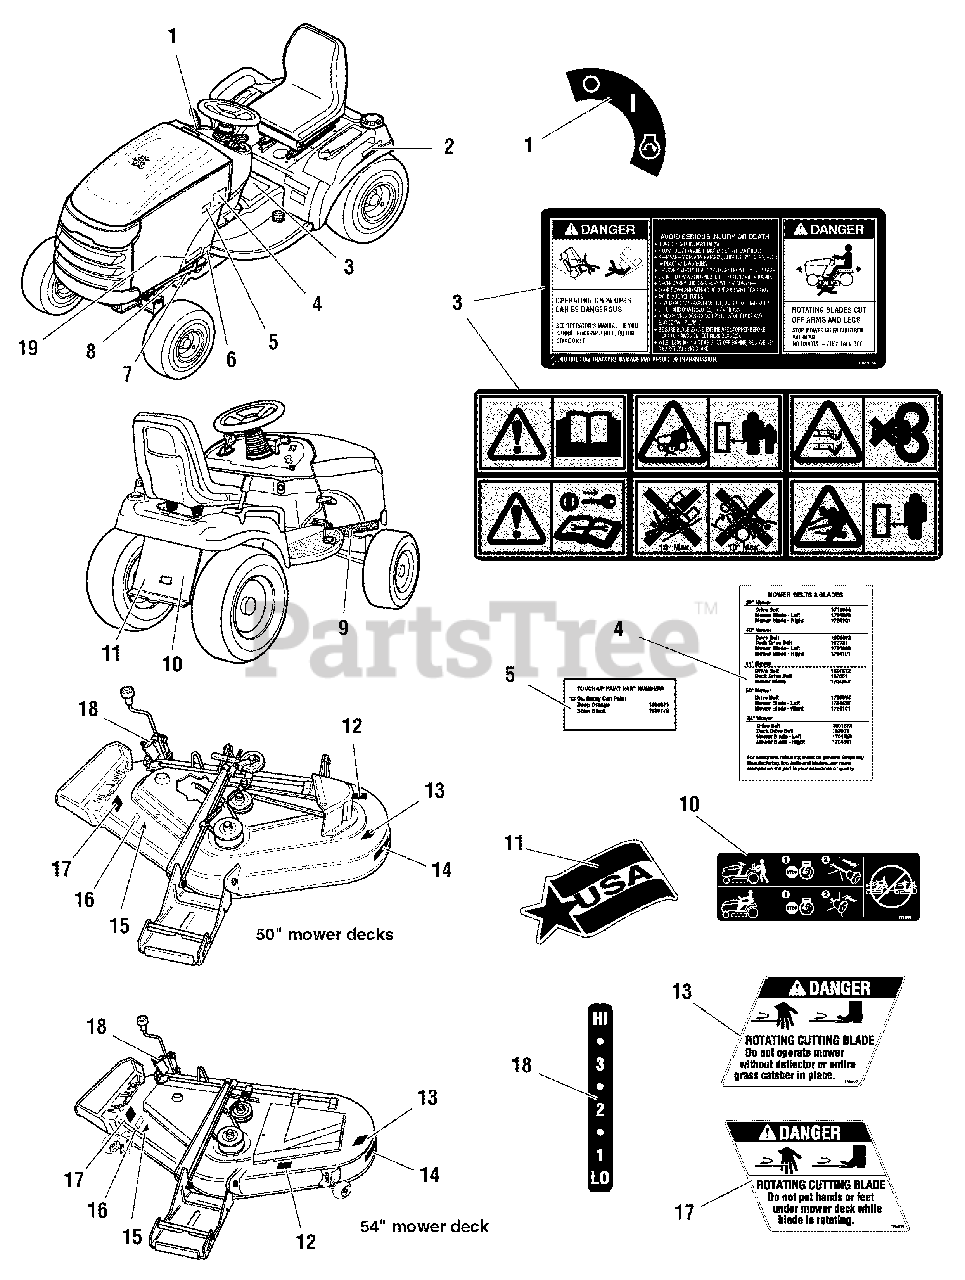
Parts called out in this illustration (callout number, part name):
1	DECAL, Ignition Switch Symbols, White/Black
2	DECAL, Automatic Control Traction
3	DECAL, Tunnel Cover, Danger Slopes/Blades
3	DECAL, Tunnel Cover, Danger Slopes/Blades, (Export)
4	DECAL, Drive Belts, Mower Blades
5	DECAL, Touch Up Paint, Deep Orange
5	DECAL, Touch Up Paint, Red
6	DECAL, Protective Sticker
7	DECAL, I.D. Plate
8	LABEL, Decibel, Power Mass (Export Only)
9	DECAL, Patent
10	DECAL, Transmission Release Valve
11	DECAL, USA Logo Stars & Stripe
12	DECAL, I.D. Plate
13	DECAL, Danger Do Not Operate Without Deflector
14	DECAL, Free Floating Mower, Silver
15	DECAL, OPEI Certified
16	DECAL, 50", Silver on Black with Stripe
16	DECAL, 54", Silver on Black with Stripe
17	DECAL, Danger Do Not Put Hands/Feet in Mower
18	DECAL, 1 2 3 4 5 6, Height of Cut
19	DECAL, Power Steering
